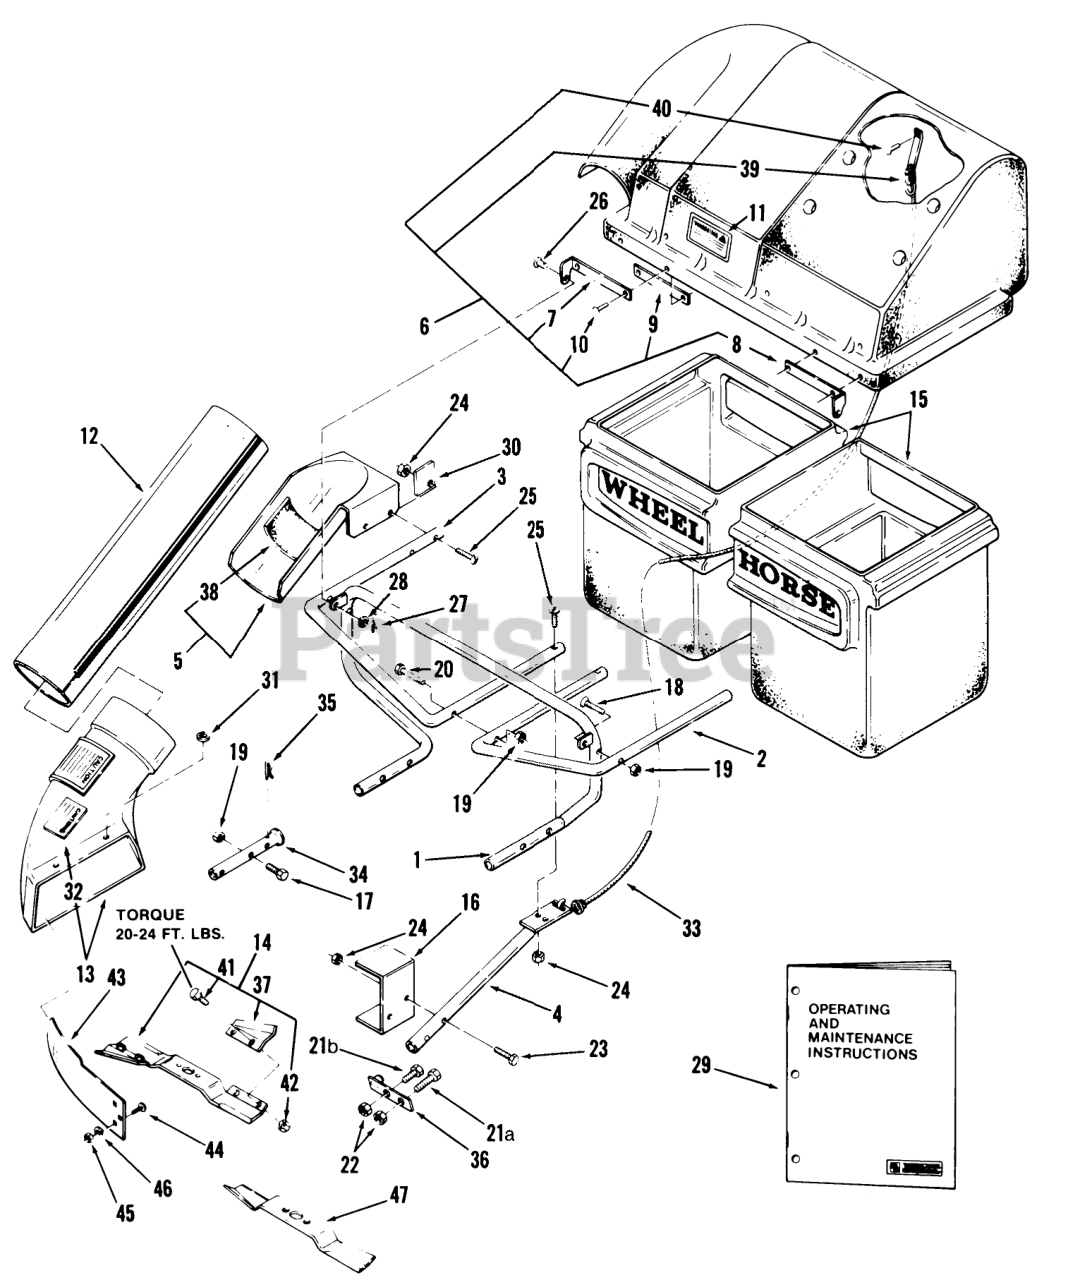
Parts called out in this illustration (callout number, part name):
1	Main Frame
2	SUPPORT-LEFT TUBE
3	Support Tube R.H.
4	ASSY-BRACE TUBE
5	Collector Tube Suport
6	Collector Top Assy.
7	Hinge R.H.
8	Hinge L.H.
9	BACKING PLATE
10	Poprivet 5/32 x 1/2 Long
11	DECAL-WARNING
12	Tube
13	ASSY-ELBOW
14	High Lift Blade
15	CAN-CLIPPINGS
16	Muffler Shield (8 HP Engine Only)
17	HHCS
18	Screw Flat Hd. Mach. 5/16 x 2 1/2
19	Nut
20	HHCS
22	Nut
23	Bolt 1/4-20 X 1 1/2
24	Nut
25	Screw Flat Hd. Mach. 1/4-20 x 1 1/2
26	PIN
27	Hairpin Cotter
28	Washer
29	Operating and Maintenance Instructions
29	Supplemental Instructions
30	PLATE-BACKUP
31	Collar
32	DECAL-CAUTION
33	Strap
34	Quick-Attach Tube
35	Pin-Cotter
36	Pin Mounting
37	Lift Tab Kit
38	Pad
39	Bracket
40	POPRIVET
41	BOLT 5/16-18X5/8
42	NUT-LOCK 5/16-18
43	BAFFLE-DEFLECTOR B
44	Bolt Carnage
45	Nut
46	Lockwasher
47	BLADE 16.50
